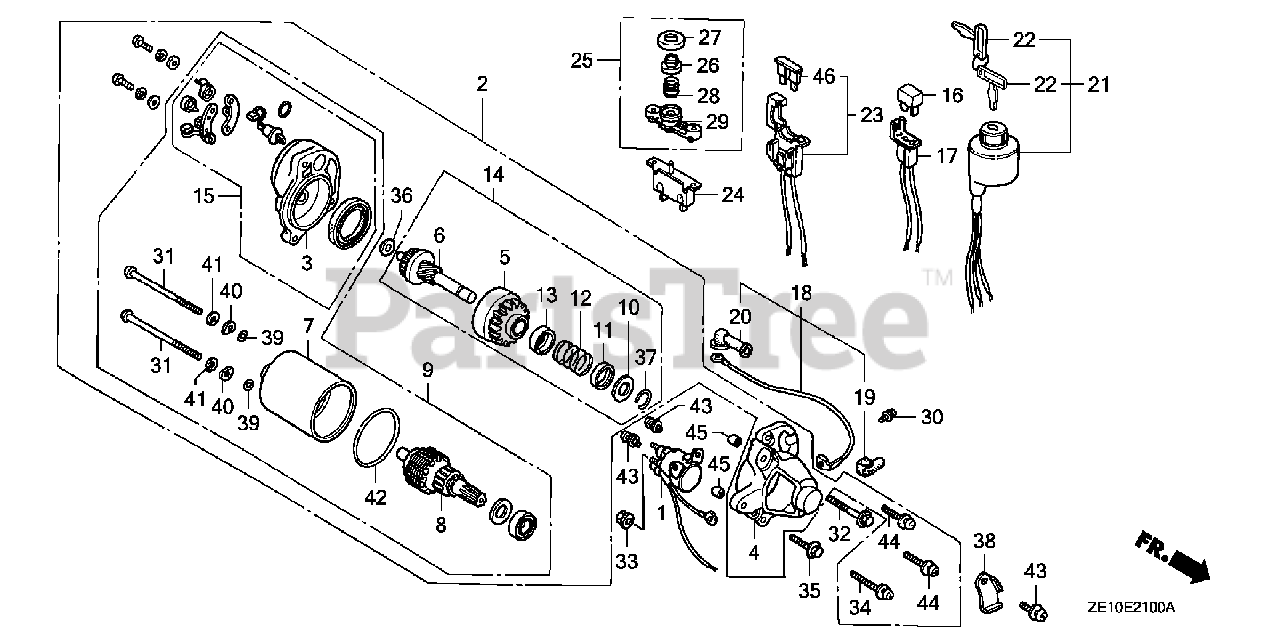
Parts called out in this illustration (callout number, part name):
1	SWITCH, STARTING MAGNET
2	STARTER MOTOR UNIT (SM-11203)
3	BRACKET, FR. Use up to Engine SN 1703215.
4	COVER, GEAR
5	PINION ASSY.
6	SHAFT UNIT, GEAR
7	YOKE ASSY.
8	ROTOR ASSY.
9	MOTOR ONLY
10	PIECE A, STOPPER
11	PIECE B, STOPPER
12	SPRING, RETURN
13	COVER, SPRING
14	GEAR ASSY.
15	BRACKET, FR.
18	WIRE, MAGNETIC SWITCH
19	COVER, MAGNETIC SWITCH
20	COVER, STARTER MOTOR TERMINAL
30	SCREW-WASHER (5X8)
31	BOLT, SETTING
32	BOLT, FLANGE (6X32)
33	NUT-WASHER (6MM)
34	SCREW-WASHER (5X30)
35	BOLT, FLANGE (6X25) (CT200)
36	WASHER, PINION
37	CIRCLIP (10.2MM)
38	HOLDER, HARNESS
40	WASHER, SPECIAL
41	WASHER, SPRING
42	O-RING Use from Engine SN 2664637.
42	O-RING Use up to Engine SN 2664636.
43	SCREW-WASHER (5X14)
44	SCREW-WASHER (5X20)
45	PIN, DOWEL (8X10)
